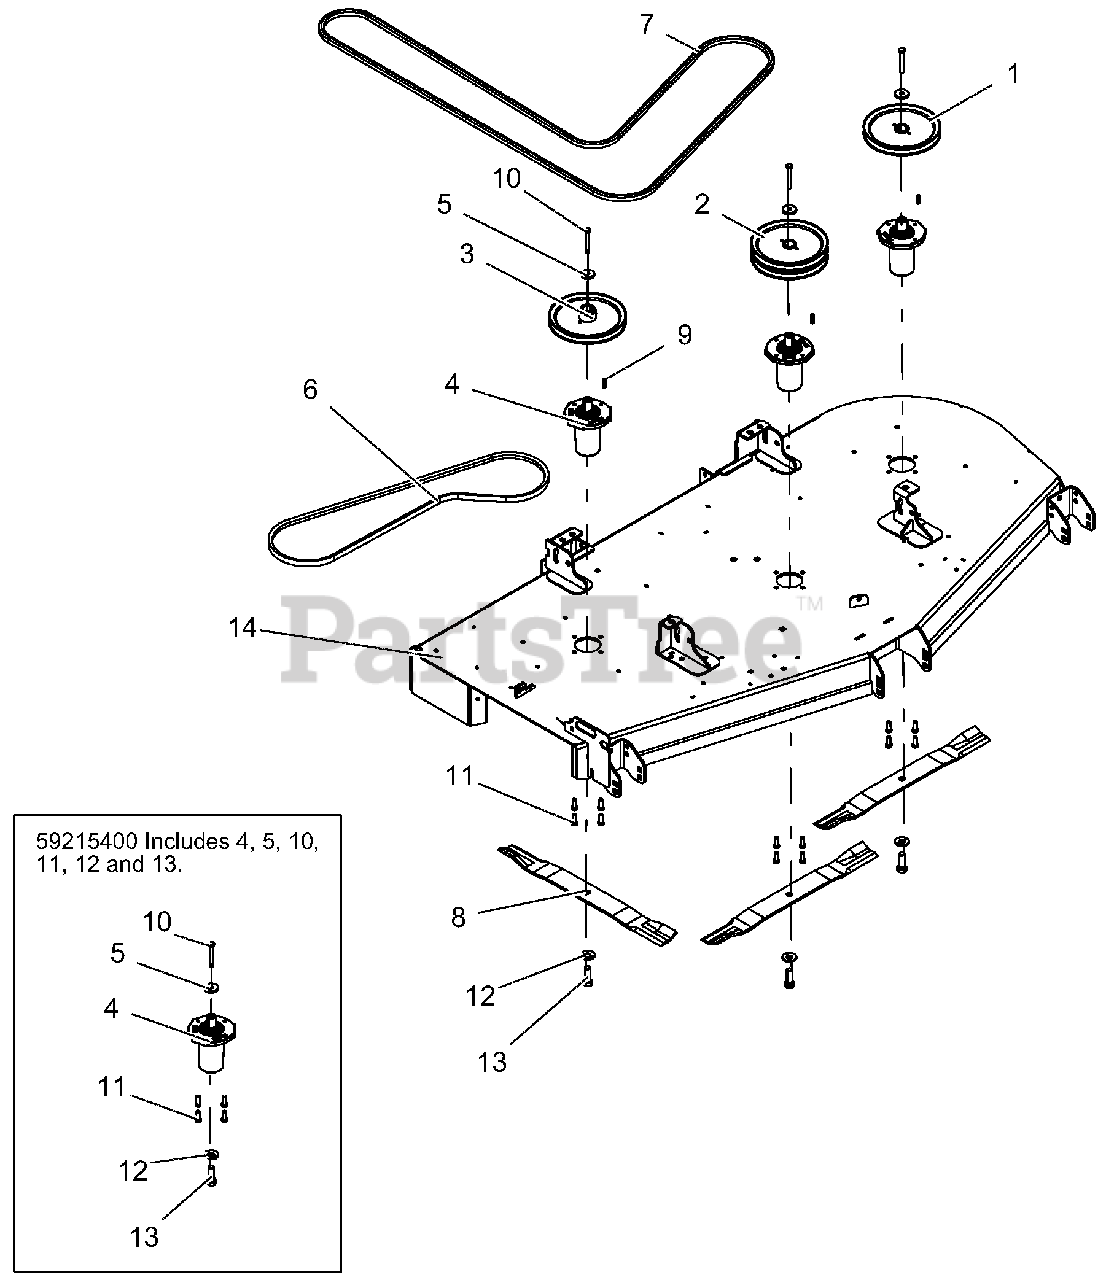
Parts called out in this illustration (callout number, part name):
1	SHEAVE-SINGLE 1.00" X 8.25" OD-BLACK
2	SHEAVE-DOUBLE 1.00"ID X 8.25"OD-BLACK
3	SHEAVE, SINGLE 1.00" ID X 8.25" OD-BLACK
4	SERVICE, ASM SPINDLE- DUCTILE
5	RETAINER, SHEAVE SPINDLE
6	V-BELT, B-COGGED
7	HEX BELT, BB-WRAPED
8	BLADE, MOWER 72" (24.5" LG)
9	KEY-SQ .250X.250X1.00 RC 40-50
10	BLT-HEX .38-16X2.75 GR8 YWZC
11	BLT-HEX .38-16X1.00 GR5 YWZC EP30
12	WSHR, BLVL .63X1.625X.14
13	BLT, HEX .62-18X1.75 GR8 YWZC
14	72" SIDE DISCH DECK W/SAFETY DECALS
